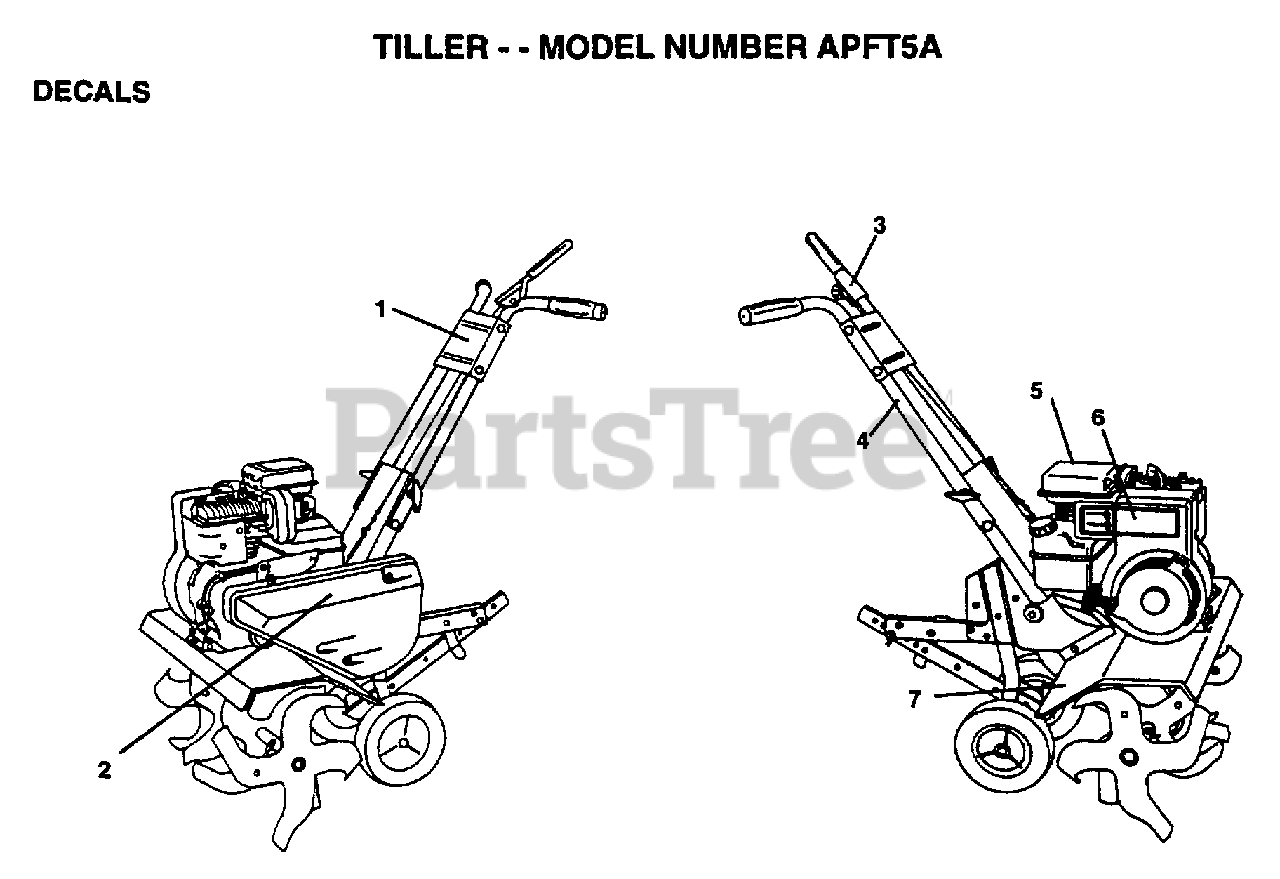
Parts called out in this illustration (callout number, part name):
1	DECAL.CNTRL.PNL.
2	DECAL.GUARD.ATLAS
3	DECAL TI
4	DECAL TI
5	DECAL TI
6	DECAL, BRIGGS & STRATTON
